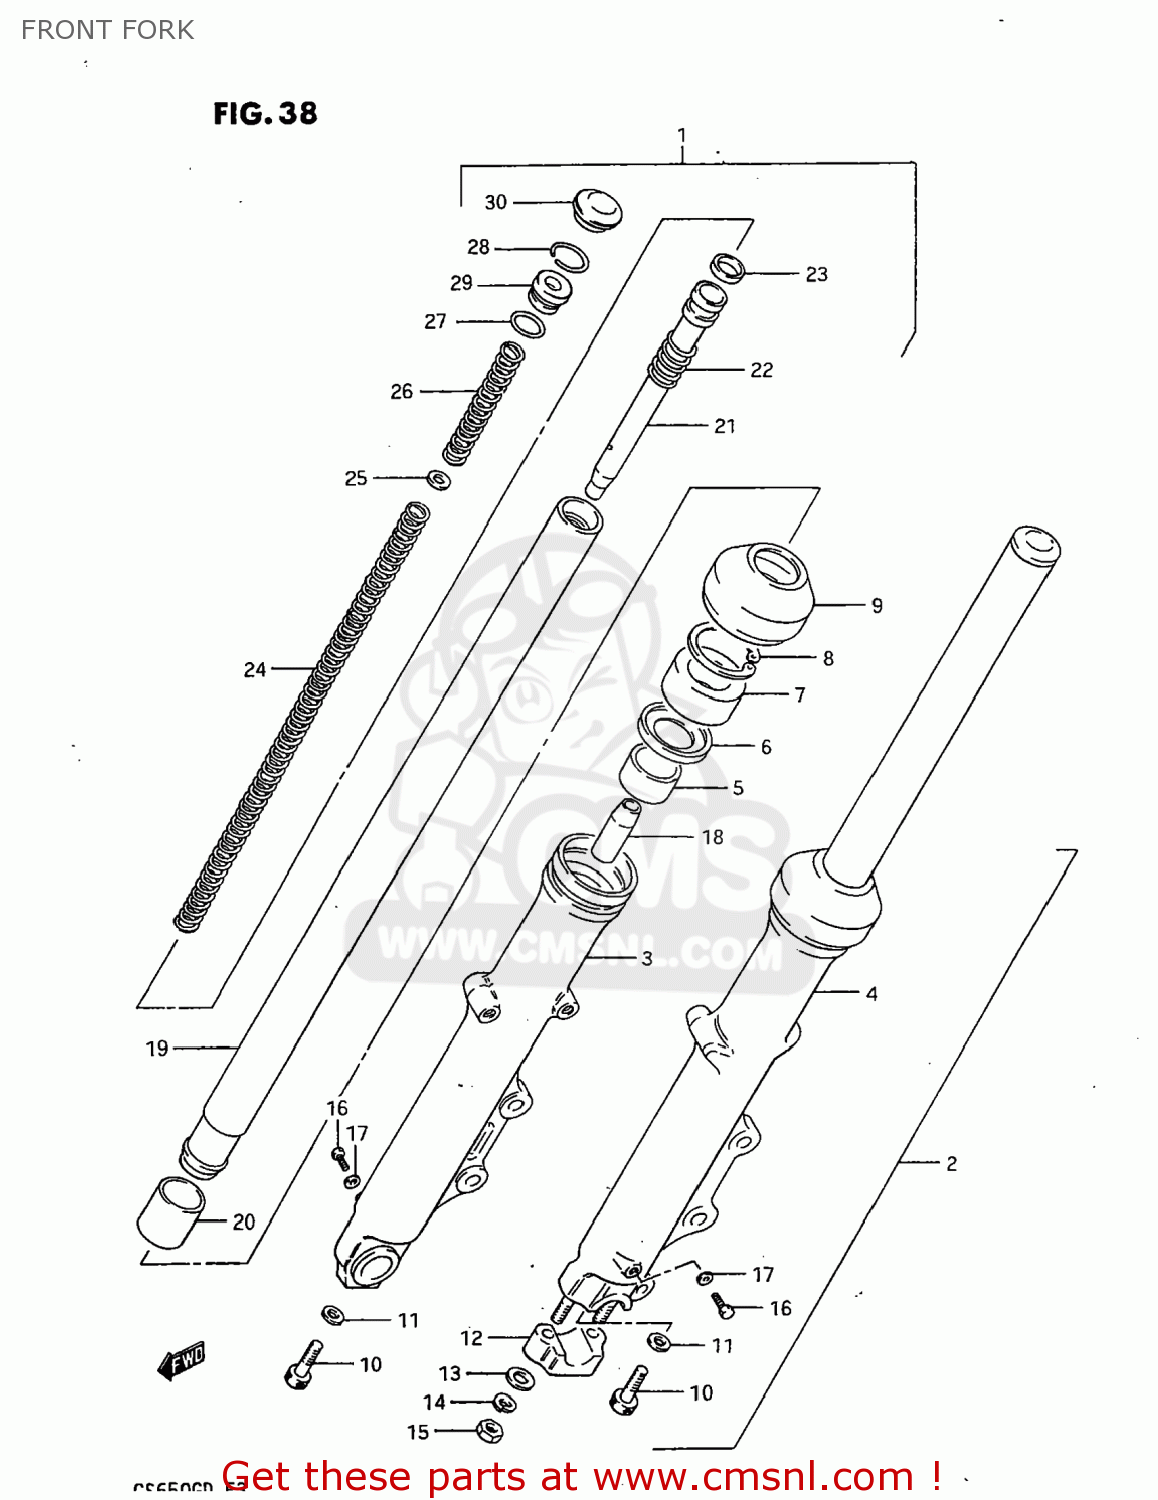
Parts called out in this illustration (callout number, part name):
1	DAMPER ASSEMBLY,RIGHT
2	DAMPER ASSEMBLY,LEFT
3	TUBE,FORK,OUTER,RIGHT
4	TUBE,FORK,LEFT,OUTER
5	BUSH,GUIDE
6	SPACER,SEAL
7	OIL SEAL,FRONT FORK
8	CIRCLIP,FORK OIL SEAL
9	BOOT
10	BOLT(8X27)
11	GASKET (NAS)
12	HOLDER,AXLE
13	WASHER
14	LOCK WASHER
15	NUT
16	BOLT
17	GASKET,DRAIN,PLUG (NAS)
18	PIECE,OIL LOCK
19	TUBE,FORK,INNER
20	PISTON
21	CYLINDER,FRONT FORK
22	SPRING,FORK REBOUND
23	RING
24	SPRING,FRONT FORK,LOWER
25	WASHER,SPRING
26	SPRING,FRONT
27	O-RING
28	RING,STOPPER
29	SPRING SEAT B
30	CAP
